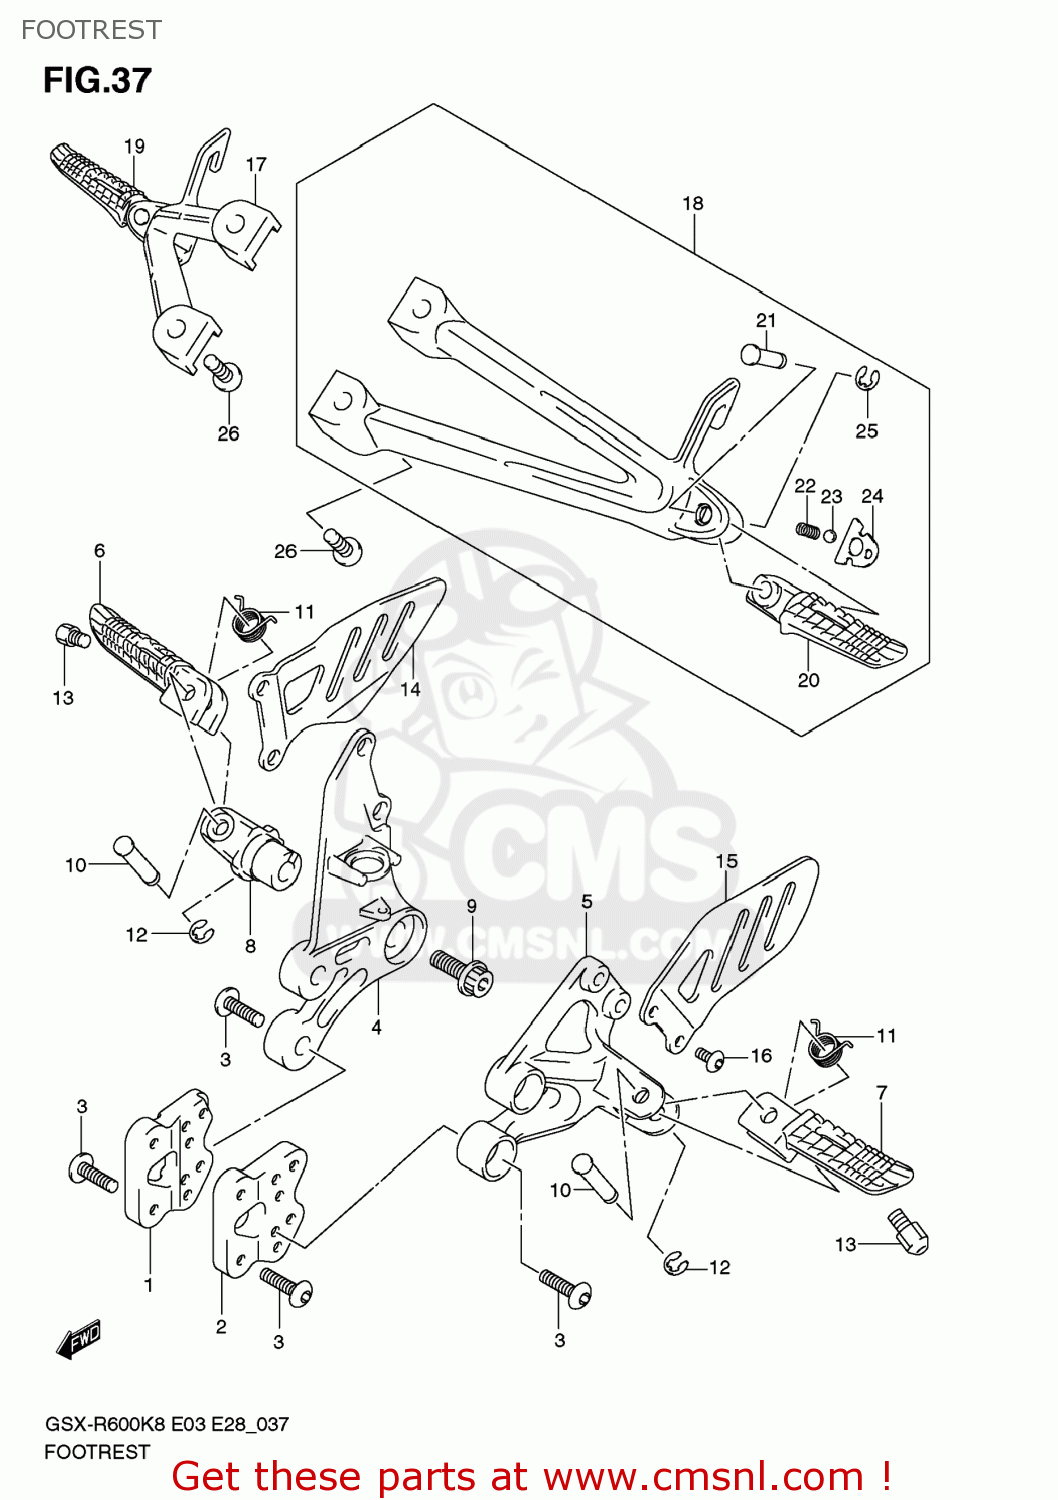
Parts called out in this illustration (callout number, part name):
1	BRACKET,FR FOOTREST NO.1,R
2	BRACKET,FR NO.1,L
3	BOLT(8X23)
4	BRACKET,FR NO.2,R
5	BRACKET,FR FOOTREST NO.2,L
6	BAR,FR FOOTREST,R
7	BAR,FR FOOTREST,L
8	HOLDER,FOOTRES
9	BOLT(10X28)
10	PIN(8X33.2)
11	SPRING
12	E RING
13	BOLT,BANK SENSOR
14	GUARD,FR FOOTR
15	GUARD,FRONT FO
16	SCREW,FOOTREST GUARD,L
17	FOOTREST ASSY,PILLION,R
18	FOOTREST ASSY,PILLION,L
19	BAR,PILLION FOOTREST,R
20	BAR,PILLION FOOTREST,L
21	PIN
22	SPRING
23	BALL
24	PLATE,PILLION
25	E RING
26	BOLT(8X23)
